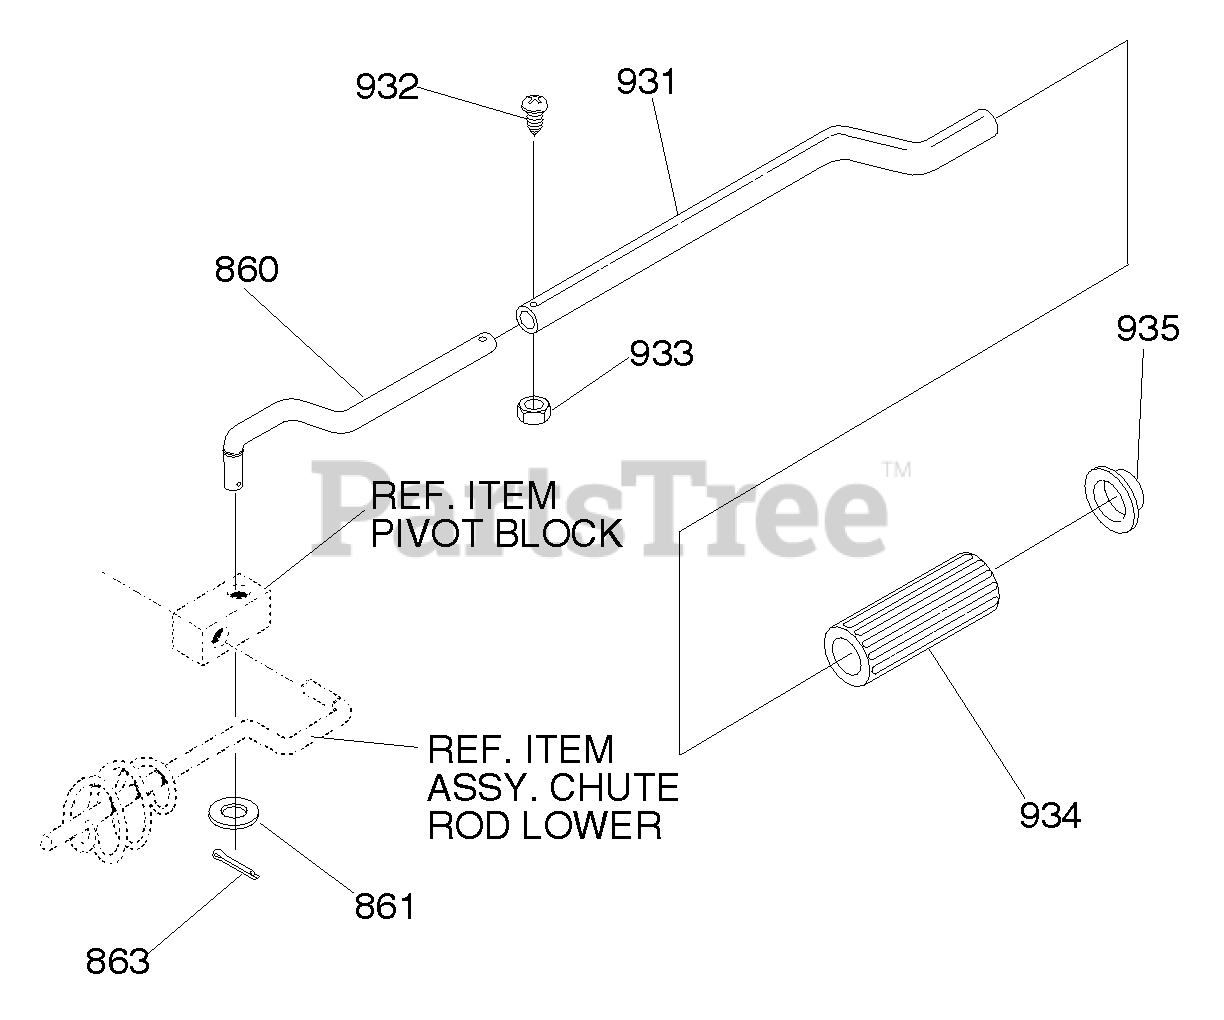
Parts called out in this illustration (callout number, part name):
860	ROD, MID CHUTE CTRL
861	FLATWASHER .40 X 75 X 025
863	COTTER PIN
931	ROD CHUTE CTRL UPPER
932	SCREW 10-32 X .88
933	NUT #10-32 CTRLK
934	KNOB, CHUTE CRANK
935	NUT, PUSH 3/8"
